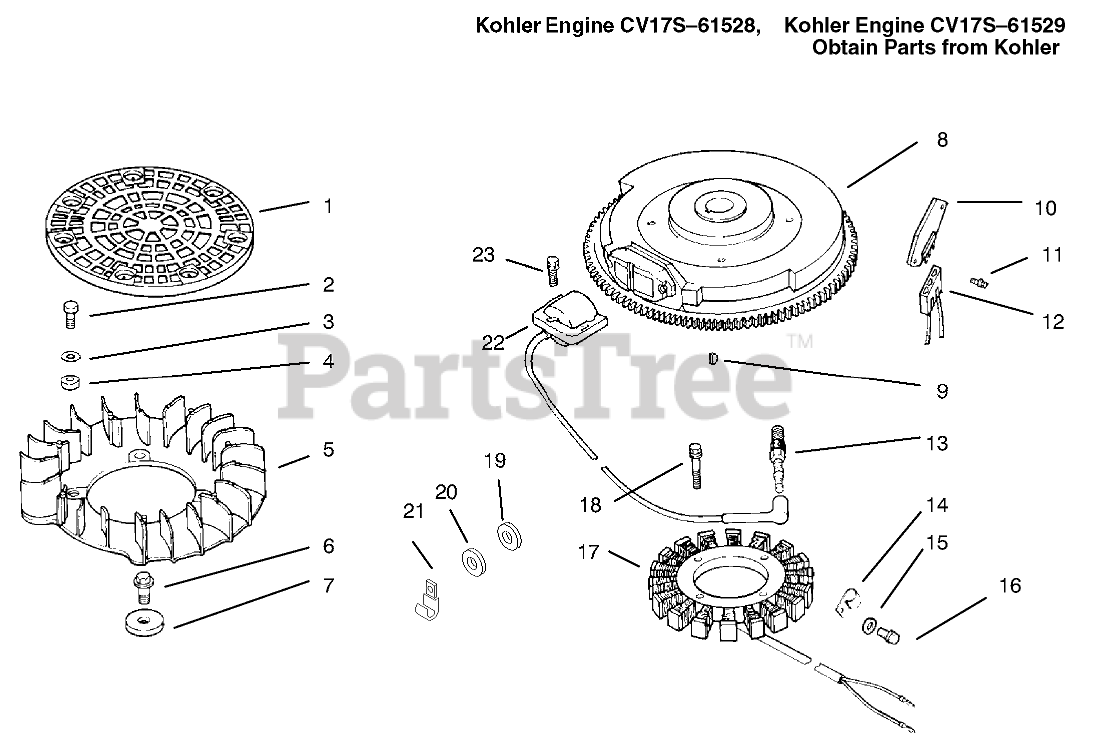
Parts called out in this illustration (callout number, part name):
1	Screen-Grass
2	Screw-Hex.
3	Washer
4	Spacer-Fan
5	Fan
6	Screw
7	Spacer
8	Flywheel
9	Key
10	Rectifier-Regulator
11	Screw
12	Connector
13	Plug-Spark
14	Clip
15	Washer
16	Screw
17	Stator-15 Amp
18	Screw
19	Washer
20	Washer
21	Clip
22	Module-Ignition
